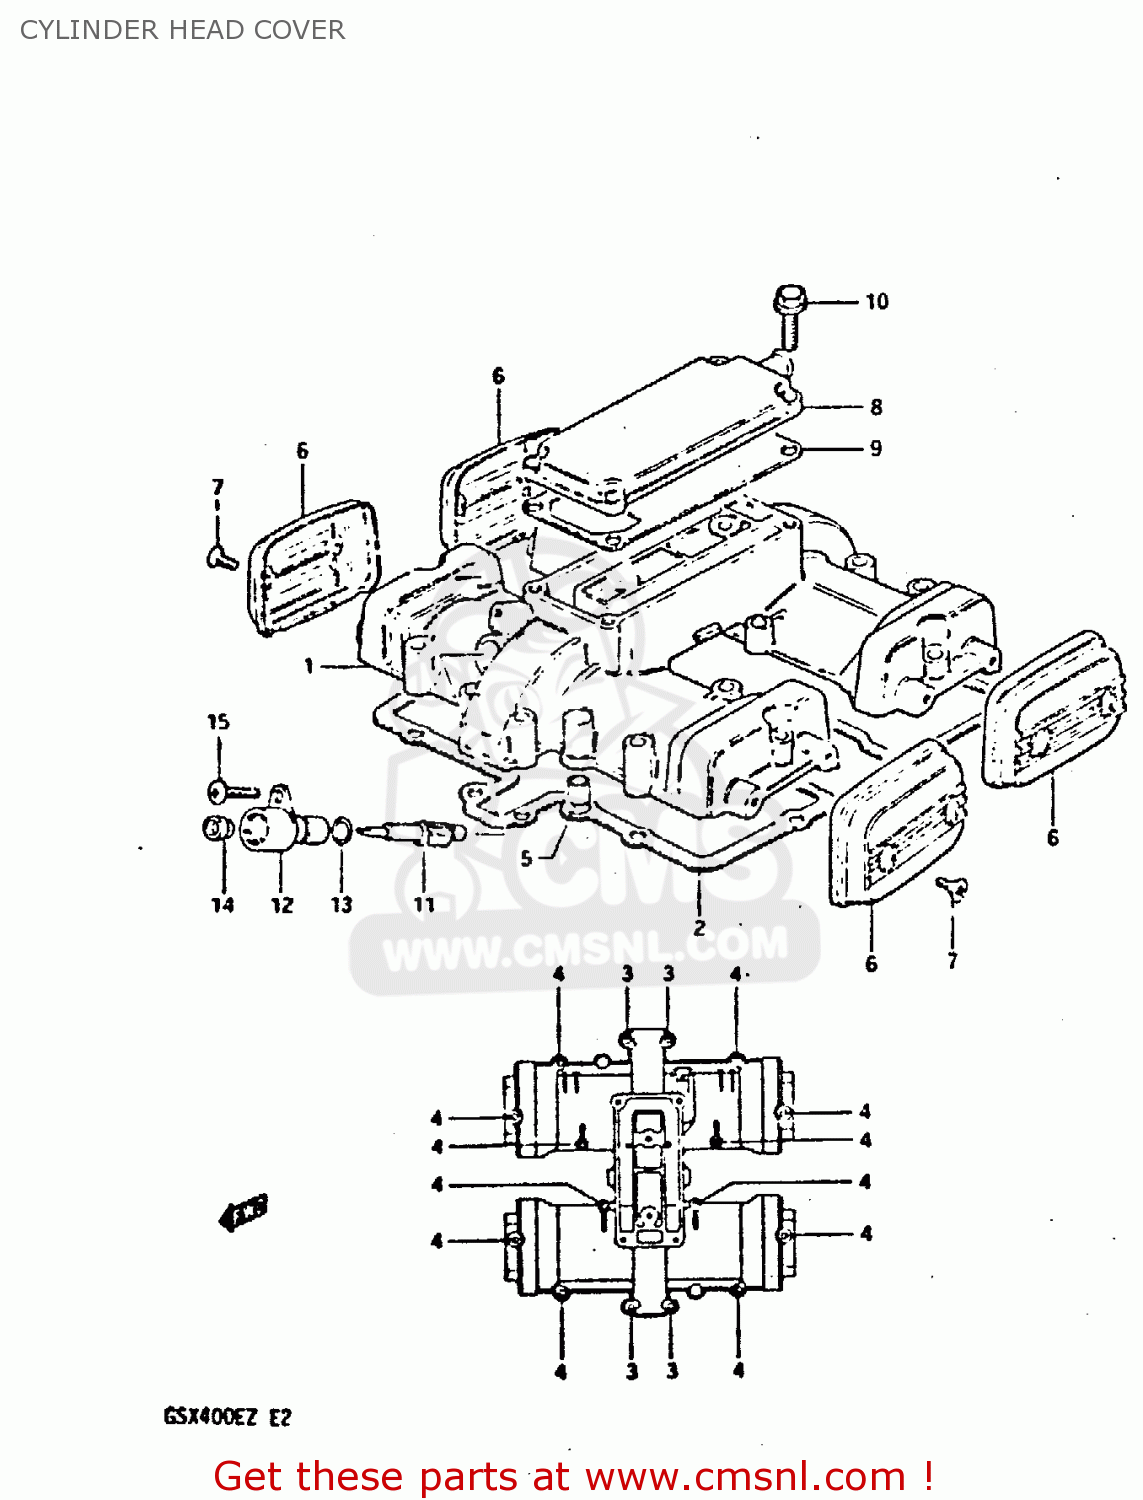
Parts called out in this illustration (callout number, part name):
1	COVER, CYLINDER HEAD
2	GASKET (MCA)
3	BOLT 6X35
4	BOLT
5	PIN(6.2X8X11)
6	CAP,CYLINDER HEAD COVER
7	SCREW(5X12)
8	COVER,BREATHER
9	GASKET (MCA)
10	BOLT,REAR
11	GEAR,TACHOMETER DRIVEN
12	SLEEVE,TACHOMETER DRIVE GEAR
13	SEAL,TACHOMETER DRIVEN
14	SEAL,OIL(5X12X8)
15	SCREW(5X12)
